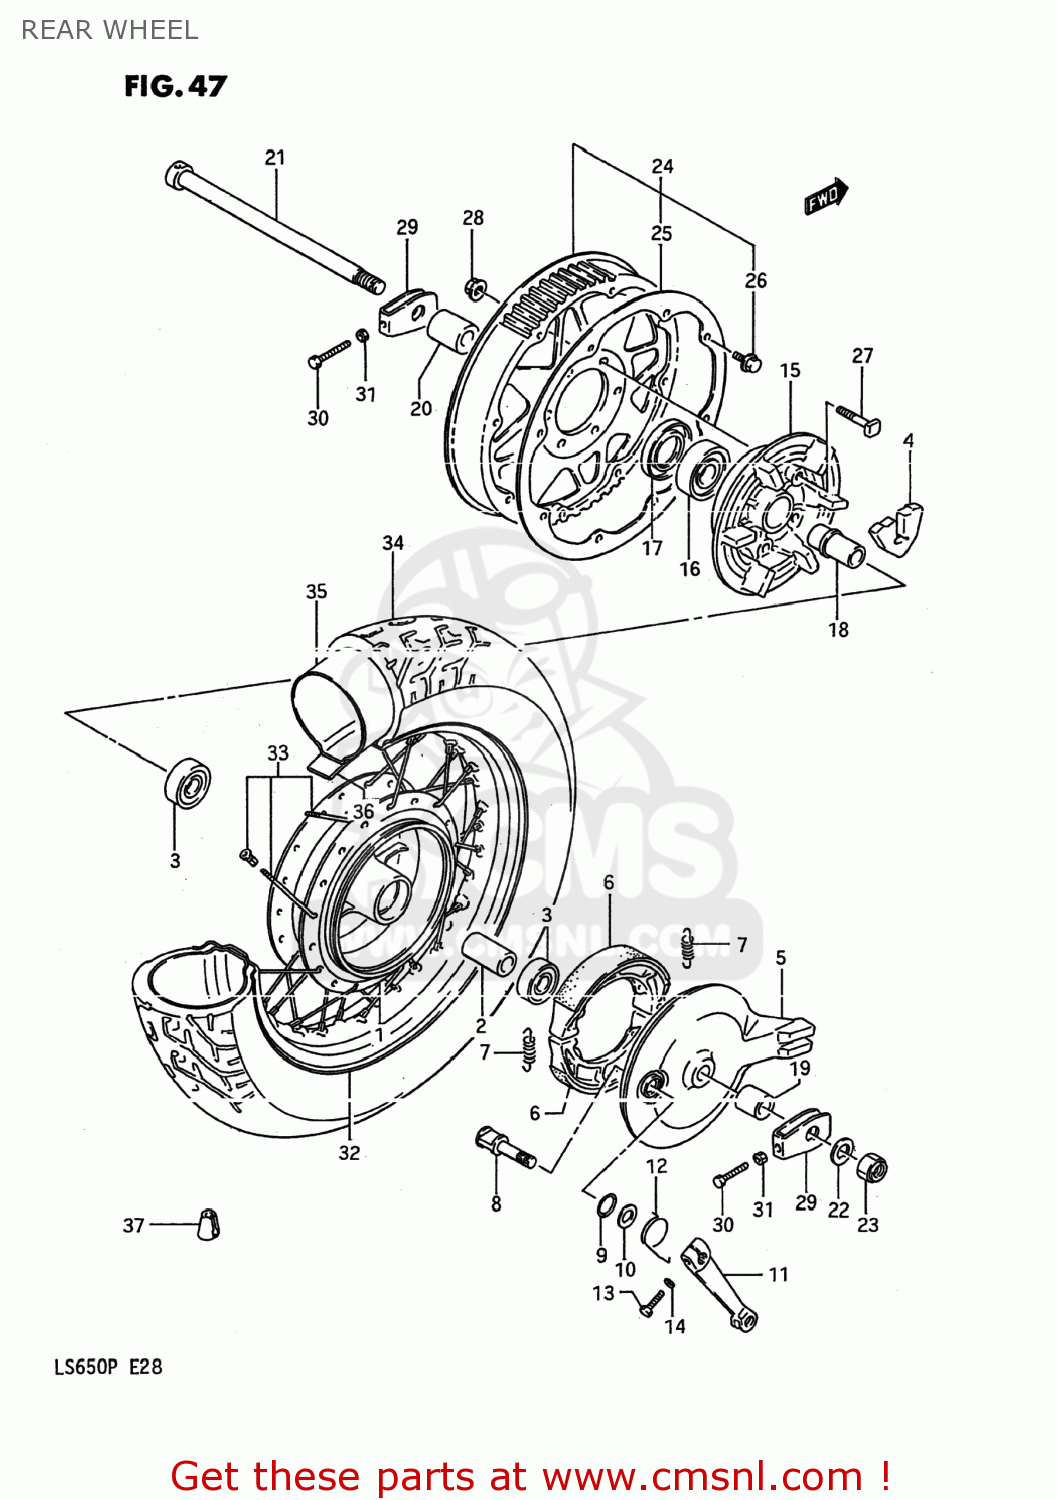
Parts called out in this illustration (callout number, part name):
1	HUB,RR WHEEL
2	SPACER(17.5X25X70)
3	BEARING
4	ABSORBER,RR HUB SHOCK
5	PANEL,REAR HUB
6	SHOE,BRAKE
7	SPRING,BRAKE SHOE
8	CAM,BRAKE
9	O-RING,BOSS
10	WASHER (15X24X1.6)
11	LEVER,RR BRAKE CAM
12	SPRING
13	BOLT
14	WASHER,LOCK
15	DRUM,RR SPROCKET MOUNTING
16	BEARING(25X62X17)
17	SEAL,OIL(33X62X7)
18	RETAINER,RR SPROCKET DRUM
19	SPACER(17X28X22.3)
20	SPACER(17X33X35.3)
21	AXLE,REAR
22	WASHER (17X30X3.2)
23	NUT
24	SPROCKET,REAR
25	PLATE,REAR SPROCKET
26	BOLT
27	BOLT(10X40)
28	NUT 10MM
29	ADJUSTER,BELT
30	BOLT 8X35
31	NUT 8MM
32	RIM,REAR WHEEL
33	SPOKE SET,RR WHEEL
34	TIRE
35	TUBE ASSEMBLY,WHEEL,INNER
36	PROTECTOR
37	BALANCER,WHEEL
